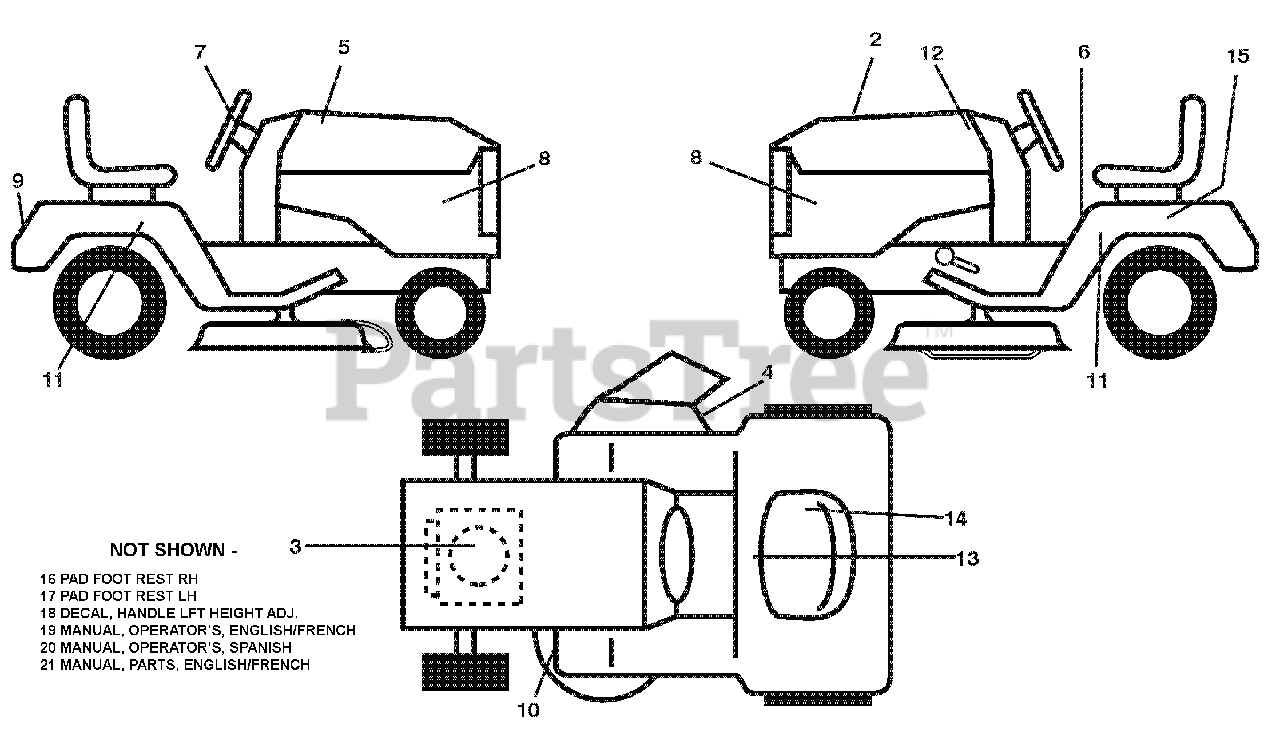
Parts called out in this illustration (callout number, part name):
2	Decal, Replacement
3	Decal, Engine HP
4	DECAL.MOWER.WARN.KEEP HAND AWY
5	Decal, Hood RH
6	DECAL.FENDER.WARNING.ENG/FR.07
7	Decal, Ins Str Wh
8	Decal, Side Panel
9	Decal, Fender
10	DECAL.V-BELT.SCH.42/46"MEC/ELE
11	Decal, Fender SD Gear Dr.
12	Decal, Hood LH
13	Decal, Flag
14	Decal, Dash Lower
15	DECAL.BAT.DAN/POI P/L SYM.WPN
